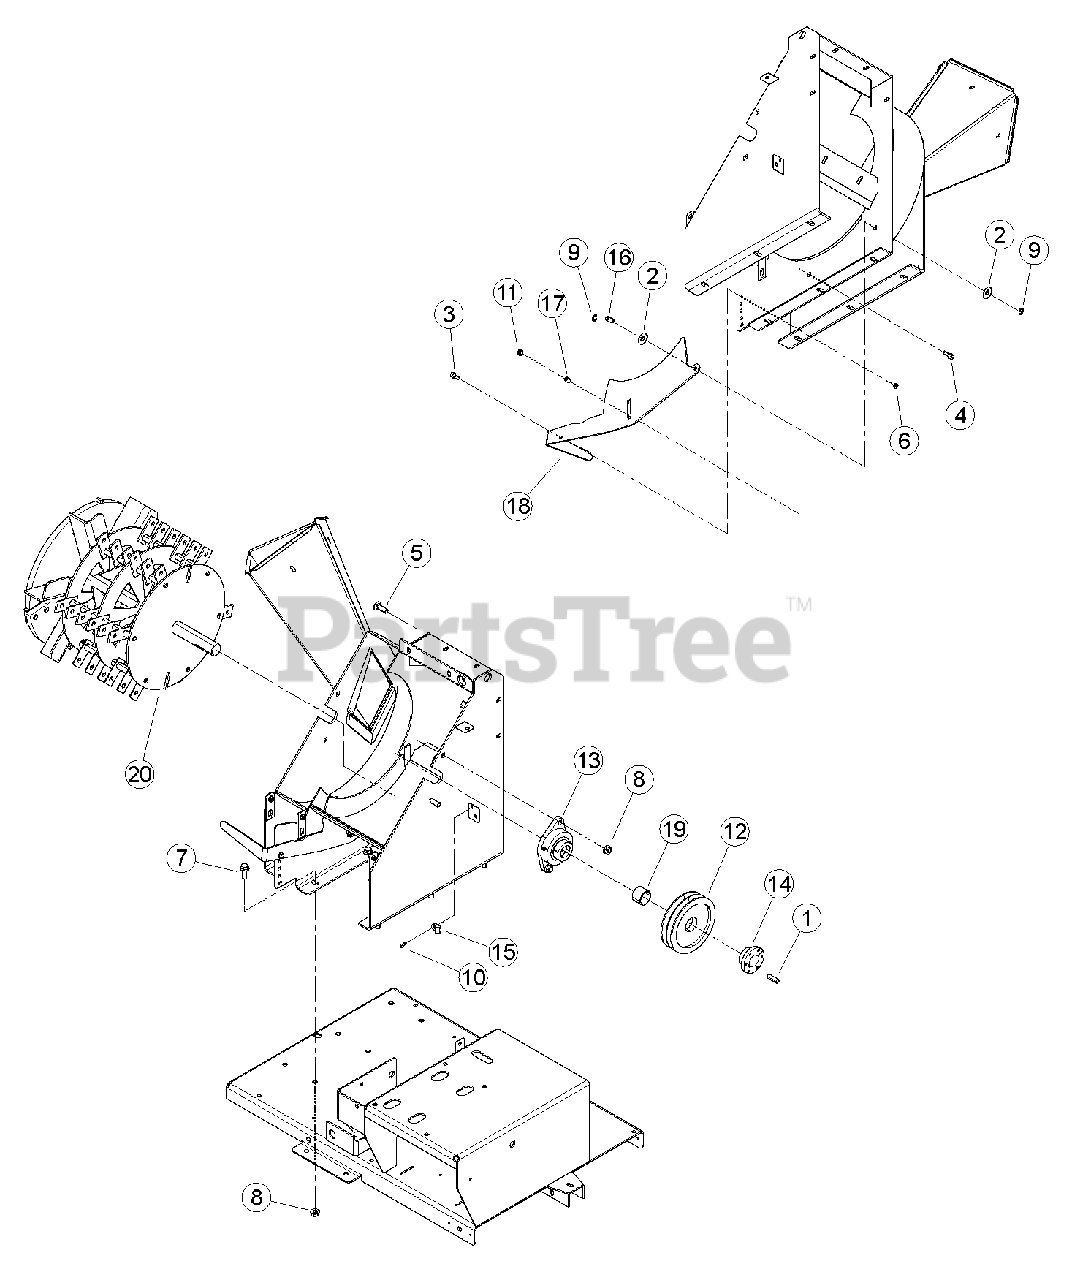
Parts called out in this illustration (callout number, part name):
1	KEY, 3/8 SQ X 1-1/2
2	WASHER, 1/2" FLAT ZP
3	BOLT, 5/16 X 3/4 FLANGE NC
4	BOLT, 5/16 X 1 FLANGE NC
5	BOLT, 1/2 X 1-1/2" GR5 ZP CRG
6	NUT, 5/16" CENTERLOCK NC ZP
7	BOLT, 1/2" X 1-1/4" SERR FLG
8	NUT, 1/2 SPIRAL LOCK NC ZP
9	CLIP, 1/2" E
10	RIVET, AL BLIND 1/4 X 3/4 DOME HEAD
11	NUT, 5/16-18 NYLOCK-FLANGE
12	SHEAVE, 2B 6.6 SDS
13	BEARING,2 BLT FLG 1-1/2" BORE
14	BUSHING, SDS 1-1/2"
15	CLAMP, CABLE MOUNT
16	PIN, RETAINER
17	SPACER, .50 X .50
18	ADJUSTOR, SHREDDER
19	SPACER, 1-3/4" OD X 1-1/2" ID X 1-1/4"
20	ASSEMBLY, 5" CS ROTOR KNIVES
